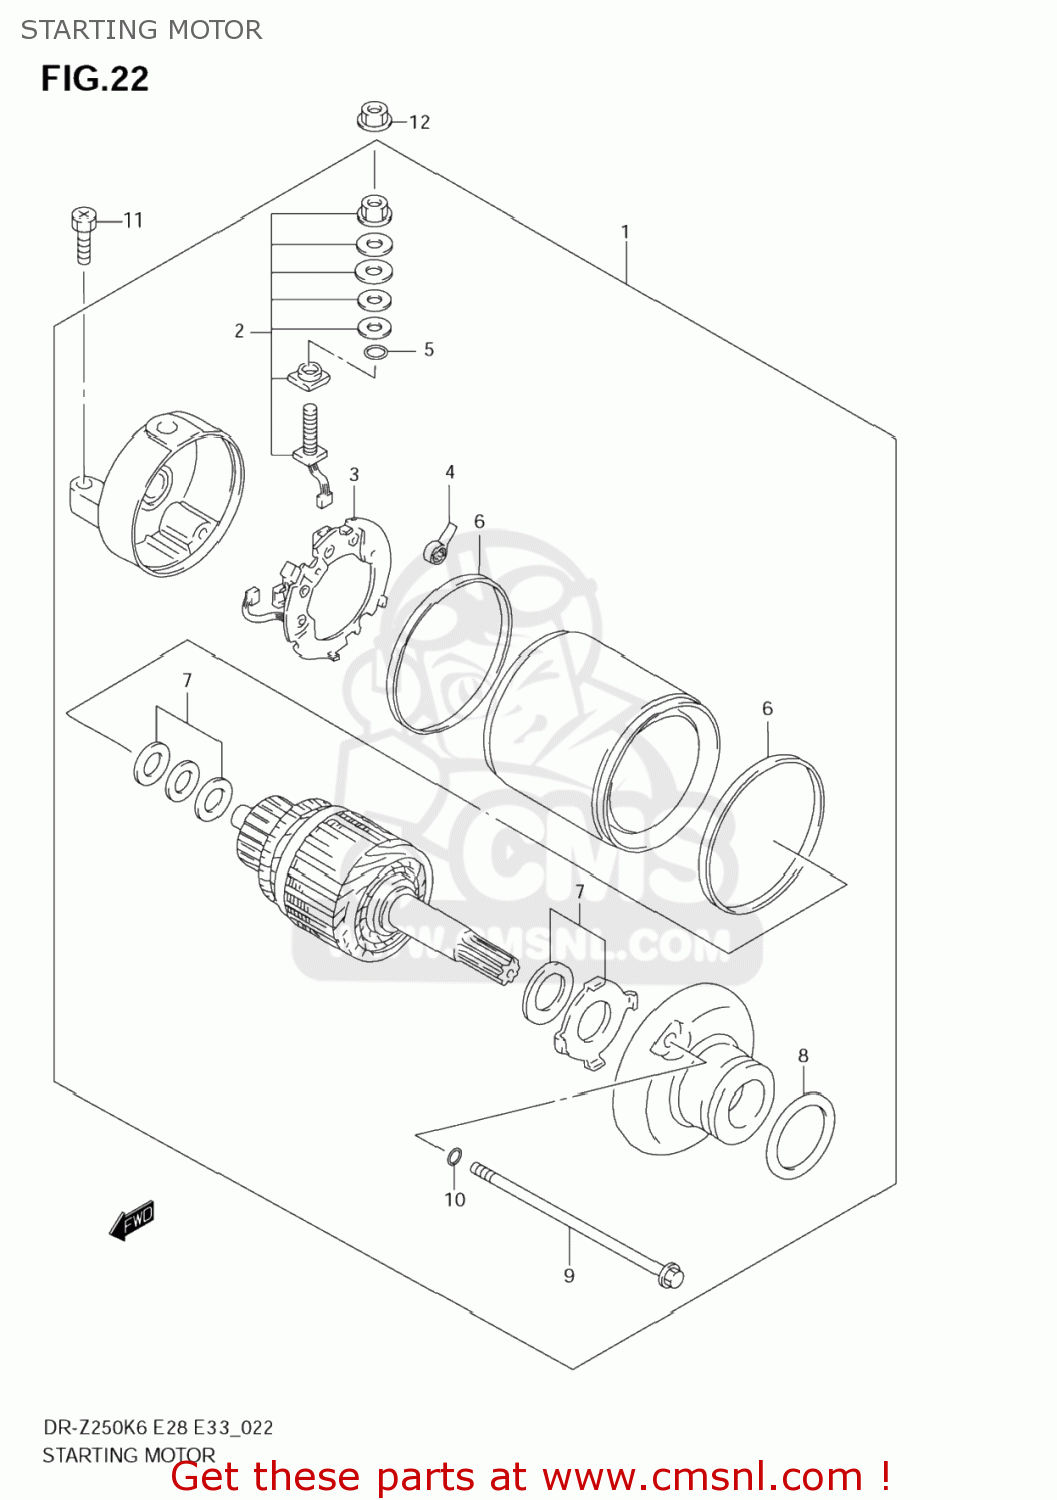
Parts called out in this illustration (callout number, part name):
1	MOTOR ASSY,STARTING
2	BRUSH TERMINAL SET
3	BRUSH HOLDER SET
4	SPRING,BRUSH
5	O RING
6	O RING
7	SHIM SET,STARTING MOTOR
8	O RING(D:3.1,ID:24.4)
9	BOLT
10	O RING
11	SCREW (6X25)
12	NUT
